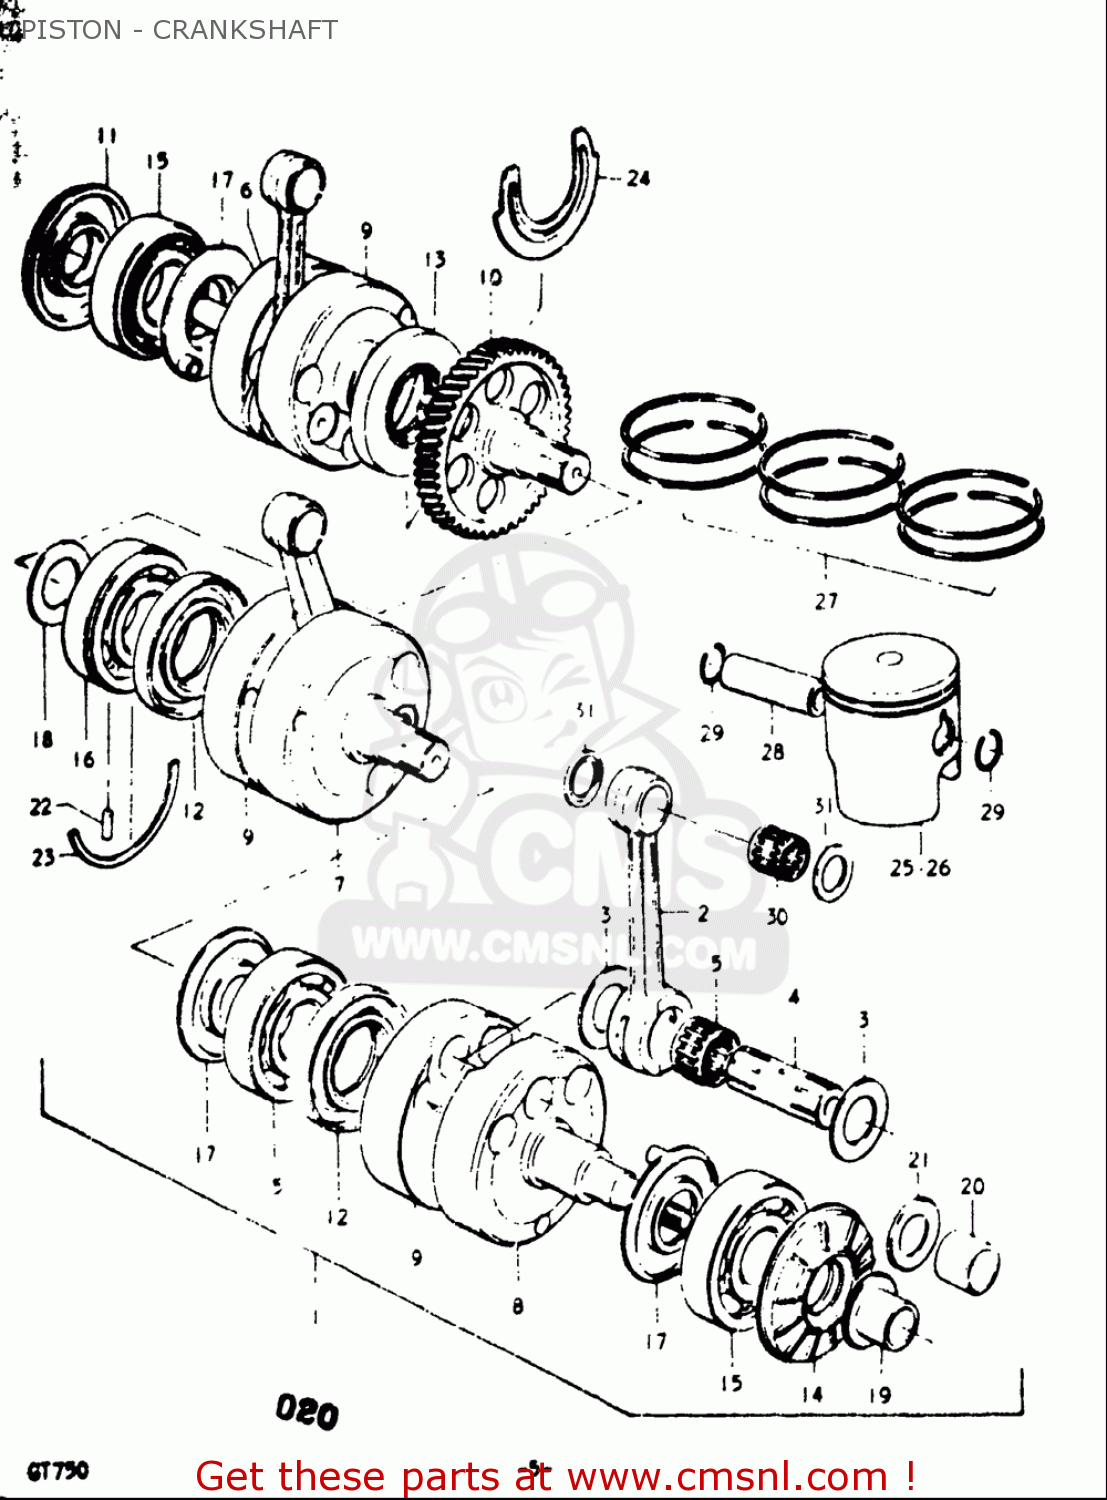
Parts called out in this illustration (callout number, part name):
2	ROD,CONNECTING
3	WASHER
4	PIN,CRANK
5	BEARING(24X30X20)
11	SEAL,OIL(25X78X8)
12	SEAL,OIL(38X78X9.5)
13	SEAL,OIL(38X78X9)
14	SEAL,OIL(30X78X8)
15	BEARING(30X78X19)
20	BUSH(20X25X20)
21	WASHER (20X40X2.5)
22	ROLLER(4X13.8)
23	C-RING
25	PISTON SET(OS:1.0)
26	PISTON,L
27	RING SET,PISTON
28	PIN,PISTON (18MM)
29	CIRCLIP,PISTON PIN
30	BEARING(18X23X24)
31	WASHER
